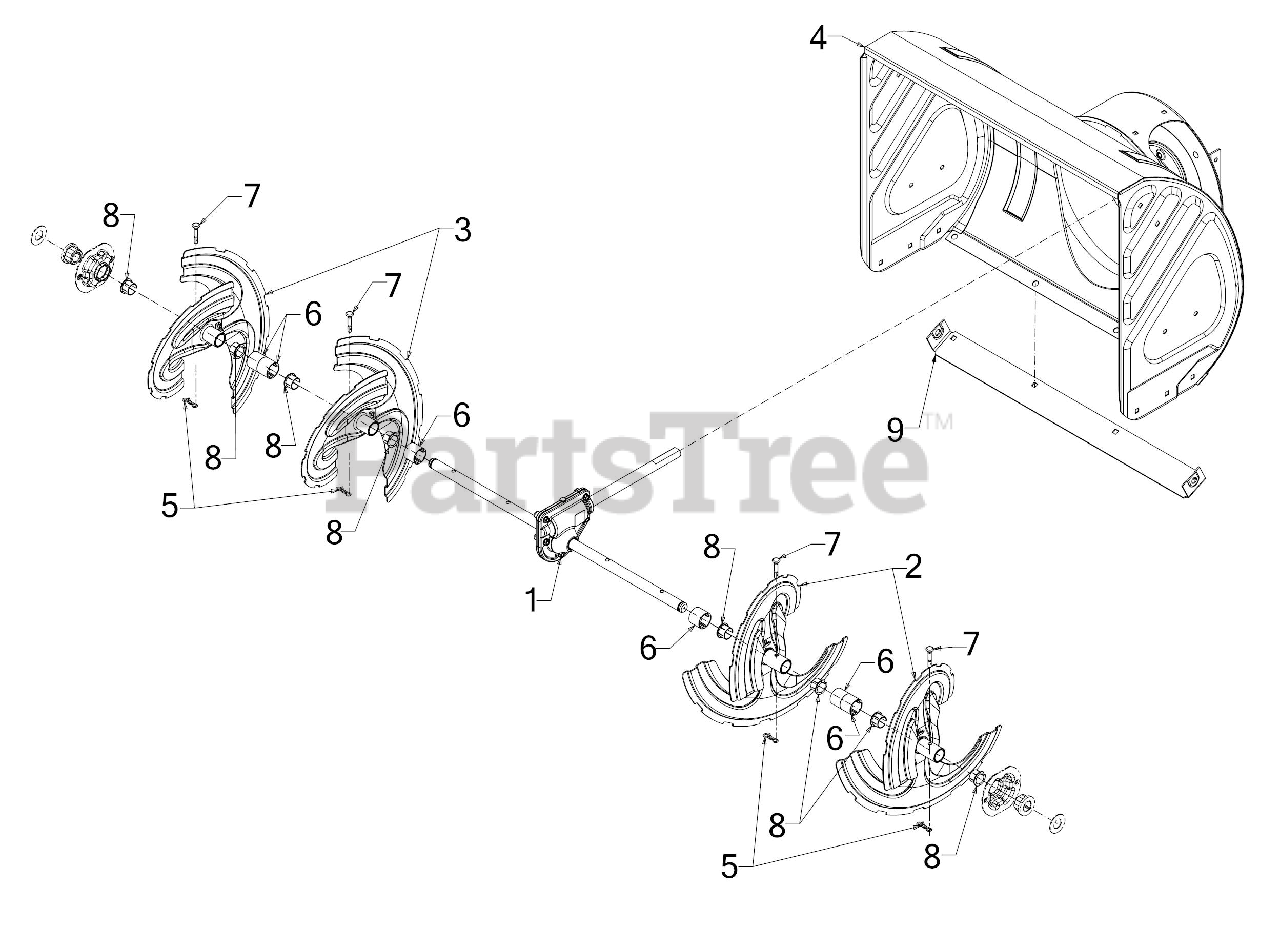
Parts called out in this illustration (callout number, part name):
1	26" GEARBOX ASSEMBLY
5	BOW TIE COTTER PIN 1/4-5/16
6	SPACER 1.25OD x .75ID X1.00 LG
7	SHEAR PIN .25 x 1.50 GR2
8	FLANGE BUSHING
